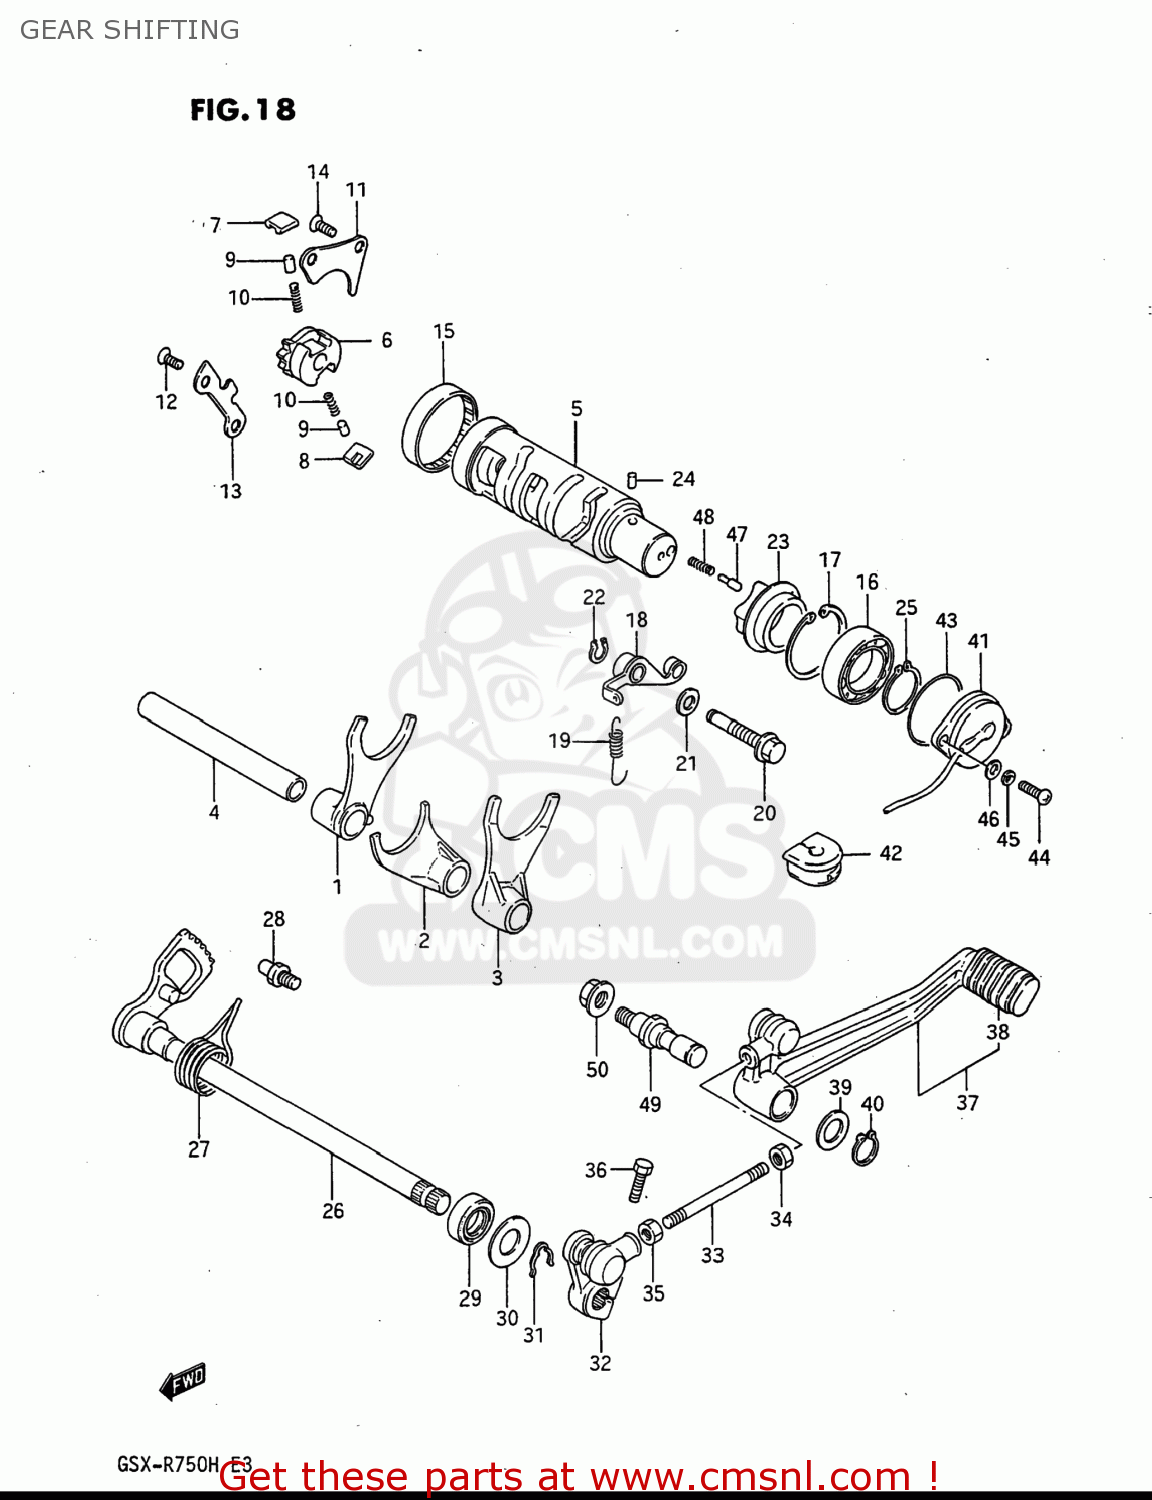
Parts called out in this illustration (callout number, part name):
1	FORK,GEAR SHIFT NO.1
2	FORK,GEAR SHIFT NO.2
3	FORK,GEAR SHIFT NO.3
4	SHAFT,GEAR SHIFT FORK(L:128)
5	CAM,GEAR SHIFT
6	GEAR,GEARSHIFT CAM DRIVE
7	PAWL,GEAR SHIFT NO.1
8	PAWL,GEAR SHIFT NO.2
9	PIN(5X8)
10	SPRING
11	LIFTER,GEAR SHIFT PAWL
12	SCREW
13	GUIDE,GEAR SHIFT CAM
14	SCREW
15	BEARING(43X49X12)
16	BALL BEARING
17	CIRCLIP,42MM
18	STOPPER,GEAR SHIFT CAM
19	SPRING
20	SHAFT,GEAR SHIFT CAM STOPPER
21	GASKET(10X14X3.6) (NAS)
22	CIRCLIP
23	PLATE,STOPPER
24	PIN 4X6
25	CIRCLIP,25MM
26	SHAFT,GEAR SHIFT
27	SPRING
28	STOPPER,GEAR SHIFT CAM
29	OIL SEAL
30	WASHER (12.5X27X1.6)
31	SPRING,RETAINER
32	ARM,GEAR SHIFT
33	ROD,GEAR SHIFT LINK
34	NUT
35	NUT 6MM
36	BOLT
37	LEVER ASSY,GEAR SHIFT
38	RUBBER,BRAKE PEDAL
39	WASHER(12.5X20X1)
40	CIRCLIP
41	TERMINAL BASE ASSY,NEUTRAL
42	GROMMET,LEAD WIRE
43	O RING(D:2.4,ID:36.5)
44	SCREW(5X14)
45	LOCK WASHER
46	WASHER
47	PIN(5X15.5)
48	SPRING
49	SHAFT,GEAR SHIFT LEVER
50	NUT
